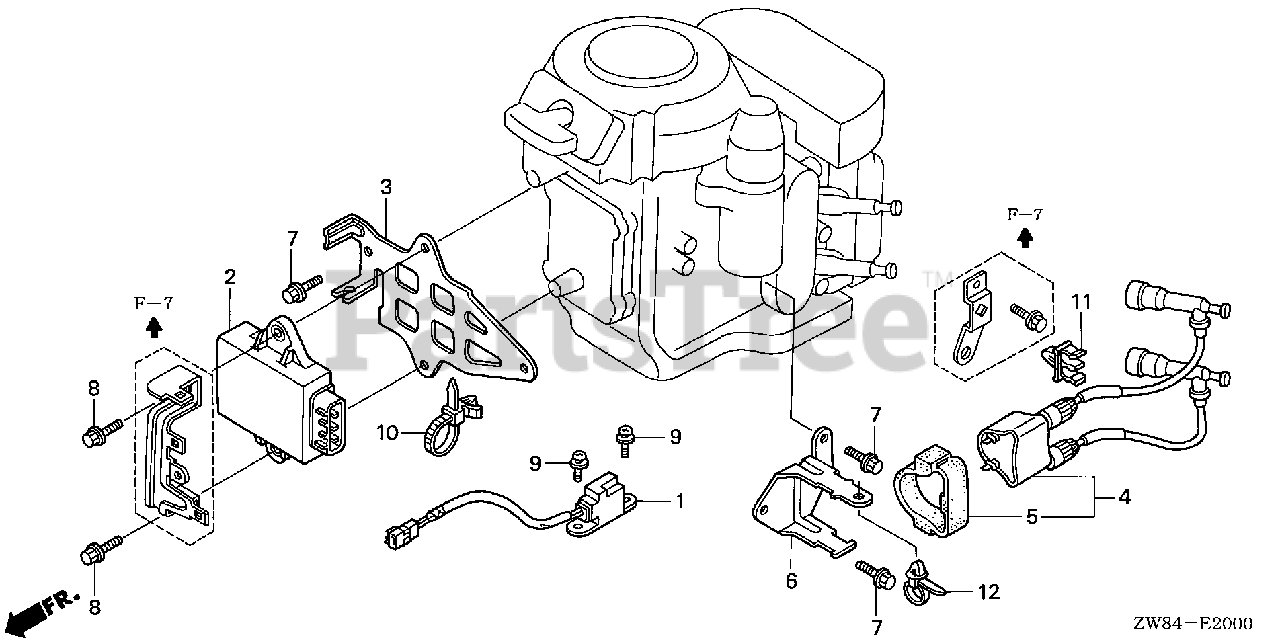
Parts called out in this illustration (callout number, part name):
1	COIL ASSY., PULSER
2	MODULE, IGNITION CONTROL (CDI)
3	PLATE, C.D.I.
4	COIL ASSY., IGNITION
5	SUSPENSION, IGNITION COIL
6	BRACKET, IGNITION COIL
7	BOLT, FLANGE (6X14) (CT200)
8	BOLT, FLANGE (6X25)
9	SCREW-WASHER (5X16)
10	STRAP, CABLE (118MM) *NH1L* (BLACK)
11	CLIP, FUEL TUBE
12	CLIP, HARNESS BAND (151.5MM) (NATURAL)
